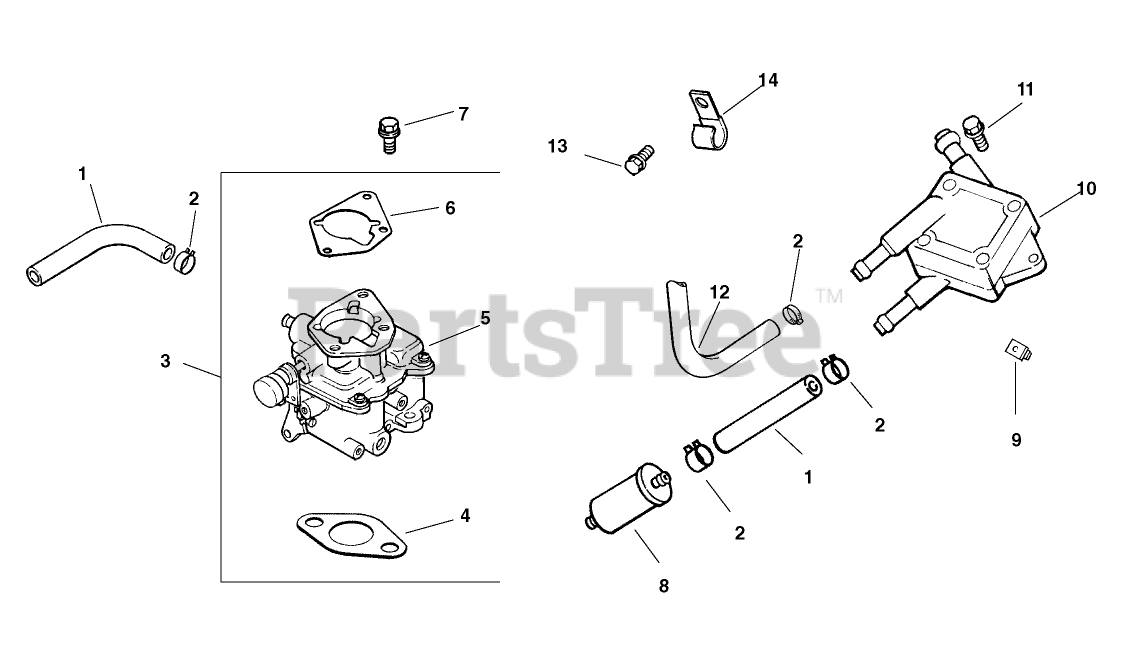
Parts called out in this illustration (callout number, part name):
1	Line-Fuel (9.5)
2	CLAMP-HOSE, SPRING (1/2)
3	Kit, carburetorw/gasket(Includes 4-6)
4	Gasket-Carburetor
5	Carburetor assembly
6	GASKET-BASE, AIR CLEANER
7	SCREW-FLANGE (M6X1.0X30)
8	Filter-Fuel
9	Nut-Plastic
10	PUMP-FUEL
11	SCREW-TAP (M6X1.7X18)
12	Line-Fuel, Flexible (15.5)
13	Screw-HF (M6x1.0x12)
14	CLIP-CABLE
16	FLOAT REPAIR KIT
